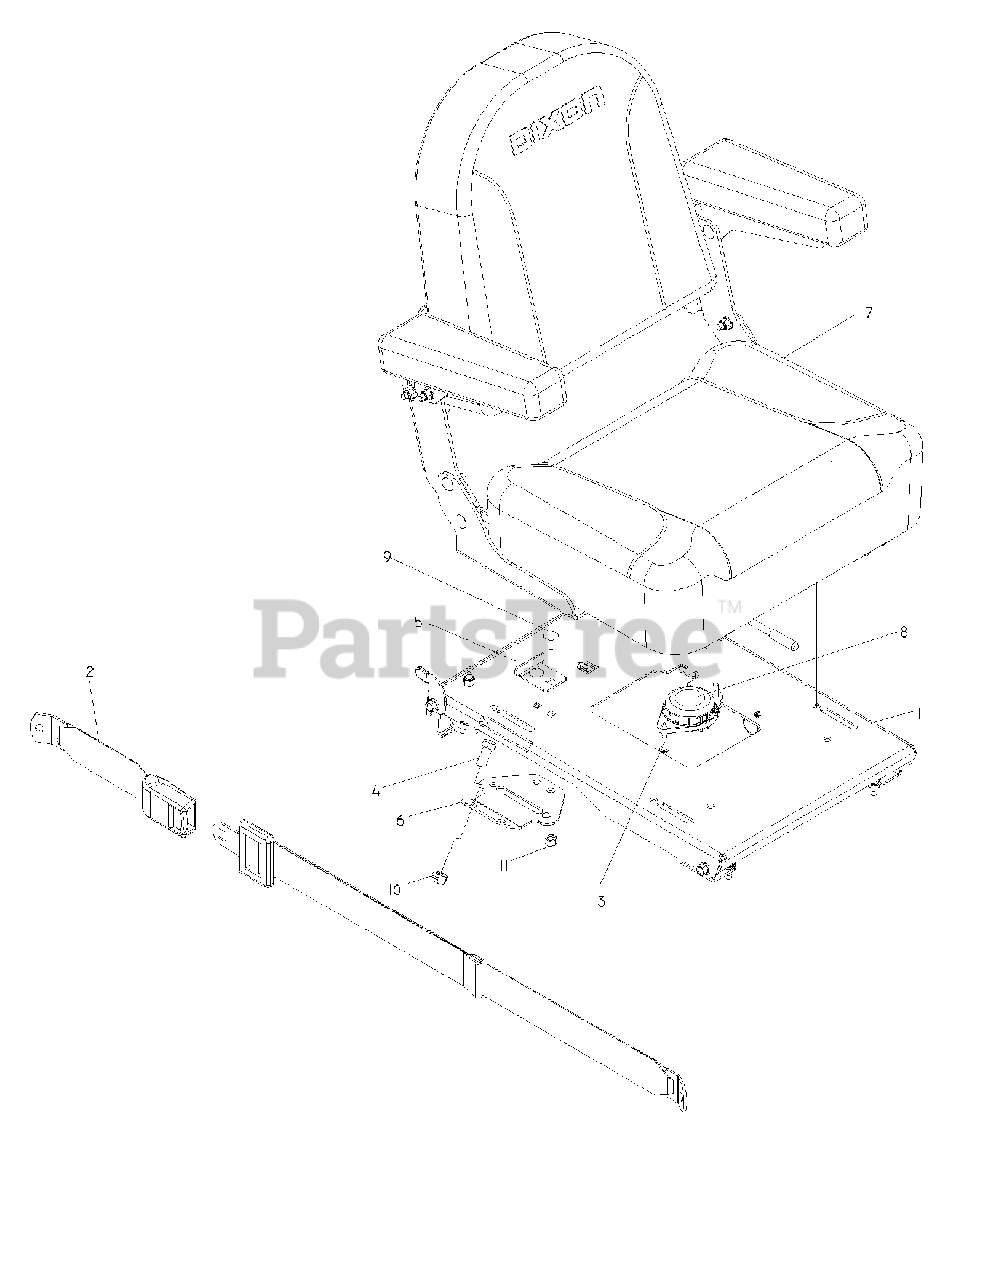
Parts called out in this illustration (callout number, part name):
2	SEAT BELT
3	SCR 1/4-20X3/4 SLTD RDHD GR2ZD
4	HCS 7/16-14 X 1 GR 5 ZD
5	STOP, SEAT - BLACK
6	MOUNT, SEAT BELT
7	SEAT ASM W/SLIDE
8	SEAT SWITCH KIT
8	SEAT SWITCH MILSCO
9	RHSNB 5/16-18 X 3/4
10	NUT 7/16C CENTERLOCK
11	NUT 5/16 NYLOC
